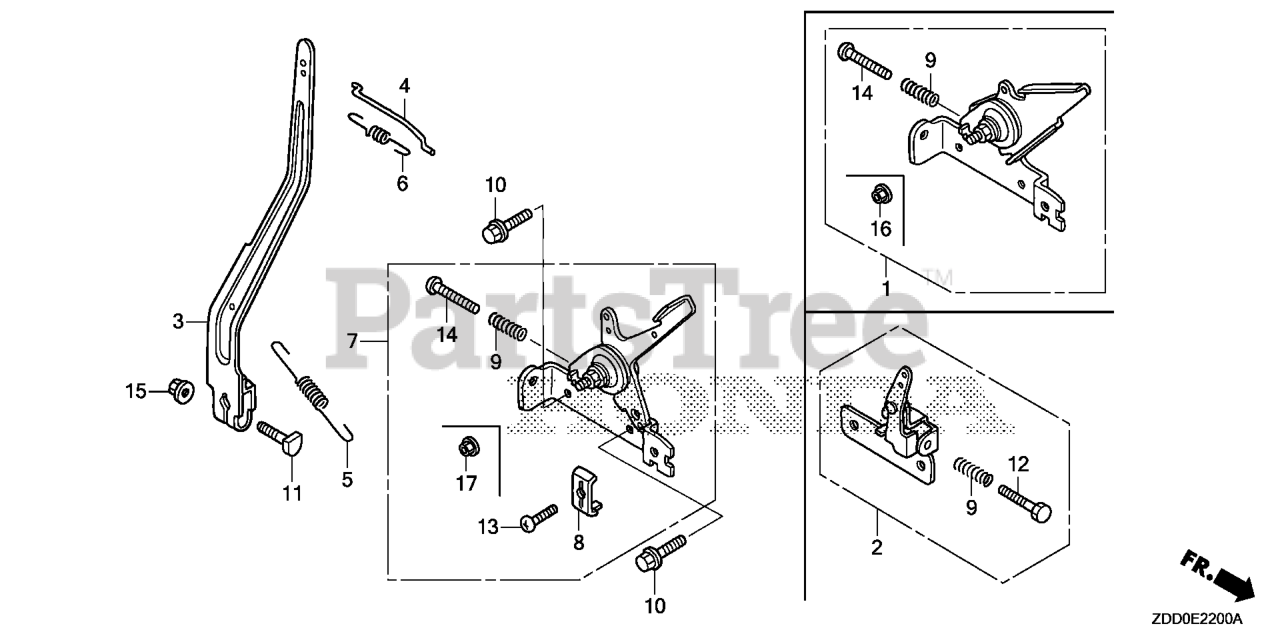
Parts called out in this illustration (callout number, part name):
3	ARM, GOVERNOR
4	ROD, GOVERNOR
5	SPRING, GOVERNOR
6	SPRING, THROTTLE RETURN
7	CONTROL ASSY. (STD)
8	HOLDER, CABLE
9	SPRING, CONTROL ADJUSTING Use from Engine SN 2327377.
10	BOLT, FLANGE (6X14)
11	BOLT, GOVERNOR ARM
13	SCREW, PAN (5X16)
14	SCREW, PAN (5X25)
15	NUT, FLANGE (6MM)
